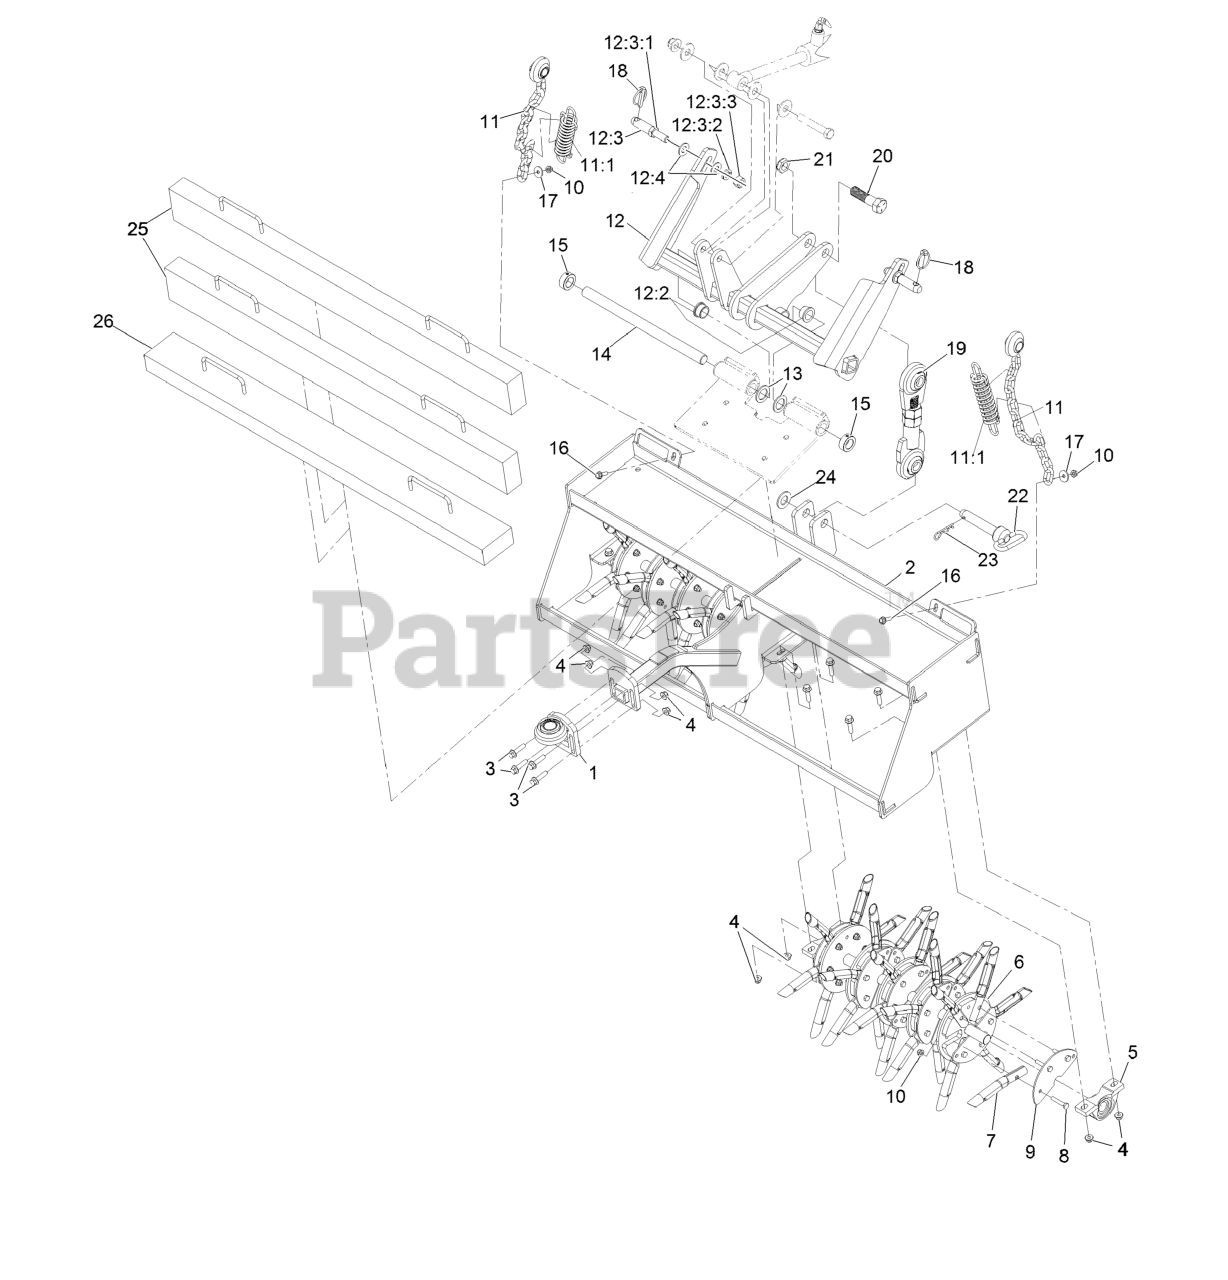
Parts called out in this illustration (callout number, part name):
1	MOUNT-SWIVEL BRG,AER HEAD
2	HEAD-AERATION, 40""
3	SCREW-HHF
4	NUT-HF, NI
5	PILLOW BLOCK BEARING
6	REEL-TINE
7	TINE-CORING (3/4 INCH)
8	SCREW-HH
9	DISK, HALF, AE
10	NUT-HF, NI
11	SWIVEL-CHAIN ASM
11:1	Z-PLUG DRAWBAR SPRING
12	ARM-LIFT, ASM
12:2	BUSHING-FLANGE
12:3	7/8 X 4-1/2 LIFT PIN\N21
12:3:1	NUT-JAM
12:3:2	WASHER-LOCK
12:3:3	NUT-HEX
12:4	WASHER-FLAT
13	WASHER-THRUST
14	PIVOT-LIFT ARM
16	SCREW-HH
17	WASHER-FLAT
18	PIN-LYNCH
19	BALL SWIVEL, ADUSTABLE LI
20	7/8-9 X 3-1/4 GR8 HEX CAP
21	NUT-LOCK, NI
22	7/8 X 4 HITCH PIN RED HAN
23	PIN-HAIR
24	WASHER-FLAT
25	112LBS WEIGHT\N45.25
26	WEIGHT-HORIZ, ZPLUG
